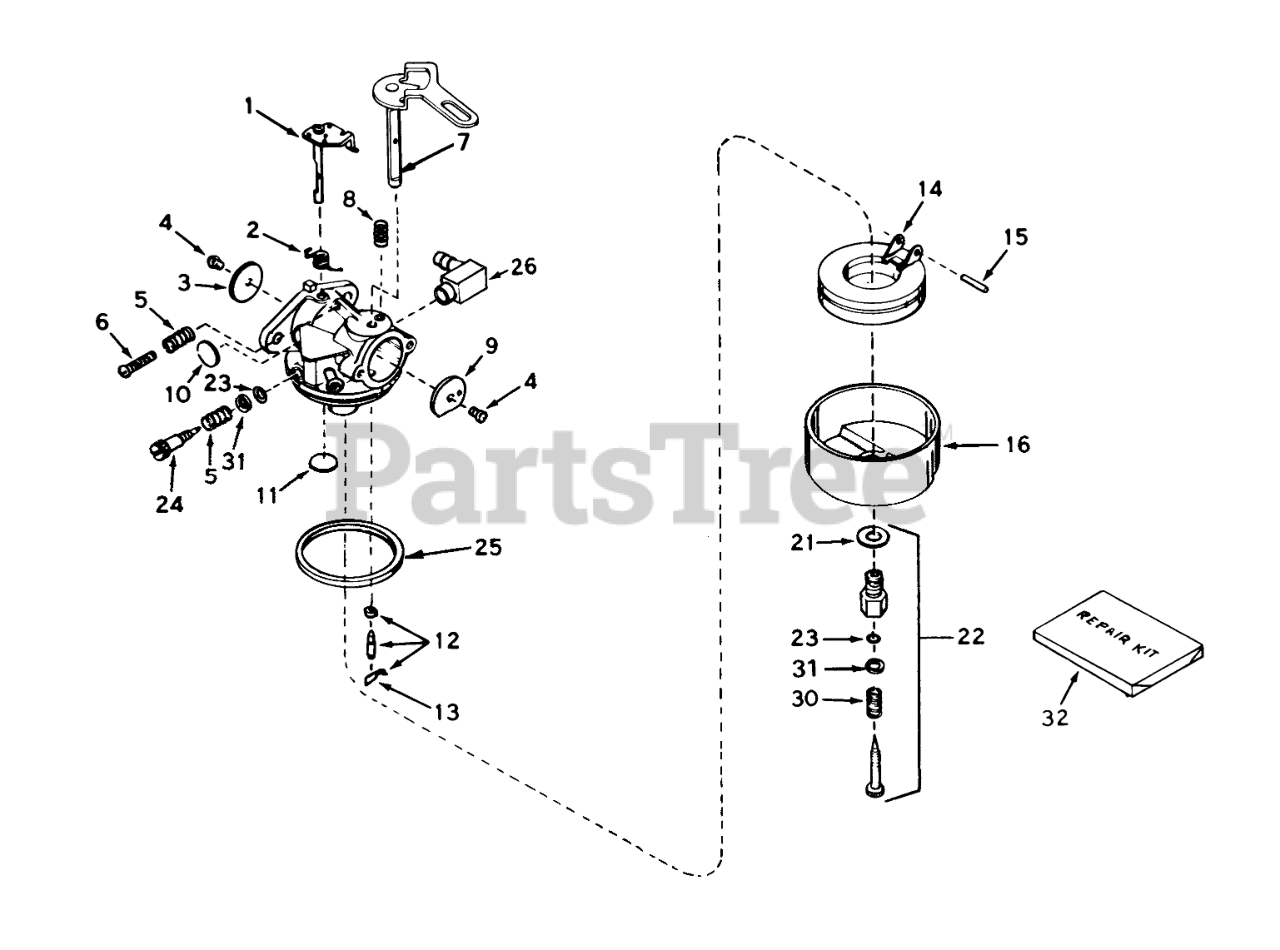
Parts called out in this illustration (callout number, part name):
1	Throttle Shaft and Lever ASM
2	Spring-Return, Throttle
3	Shutter-Throttle
4	Screw-Shutter
5	Spring-Tension
6	Screw-Throttle Crack Screw / Idle Speed
7	Choke Shaft and Lever Asm
8	Spring-Positioning, Choke
9	Shutter-choke
10	Plug-Welch, Idle Mixture Well
11	Plug-Welch, Atmospheric Vent
12	Inlet Needle-Seat & Clip Assy. (Incl. Ref. #13)
13	Clip-Spring
14	Float
15	Shaft-Float
16	Bowl-Float (no drain)
21	Washer-Bowl Nut
22	Adjustment Screw Assy.-Main (Incl. Ref. #21, 23, 30 & 31)
23	"O"Ring
24	Screw, Idle Adj.
25	O Ring-Bowl, Float
26	Fitting-Fuel
32	Kit-Repair
